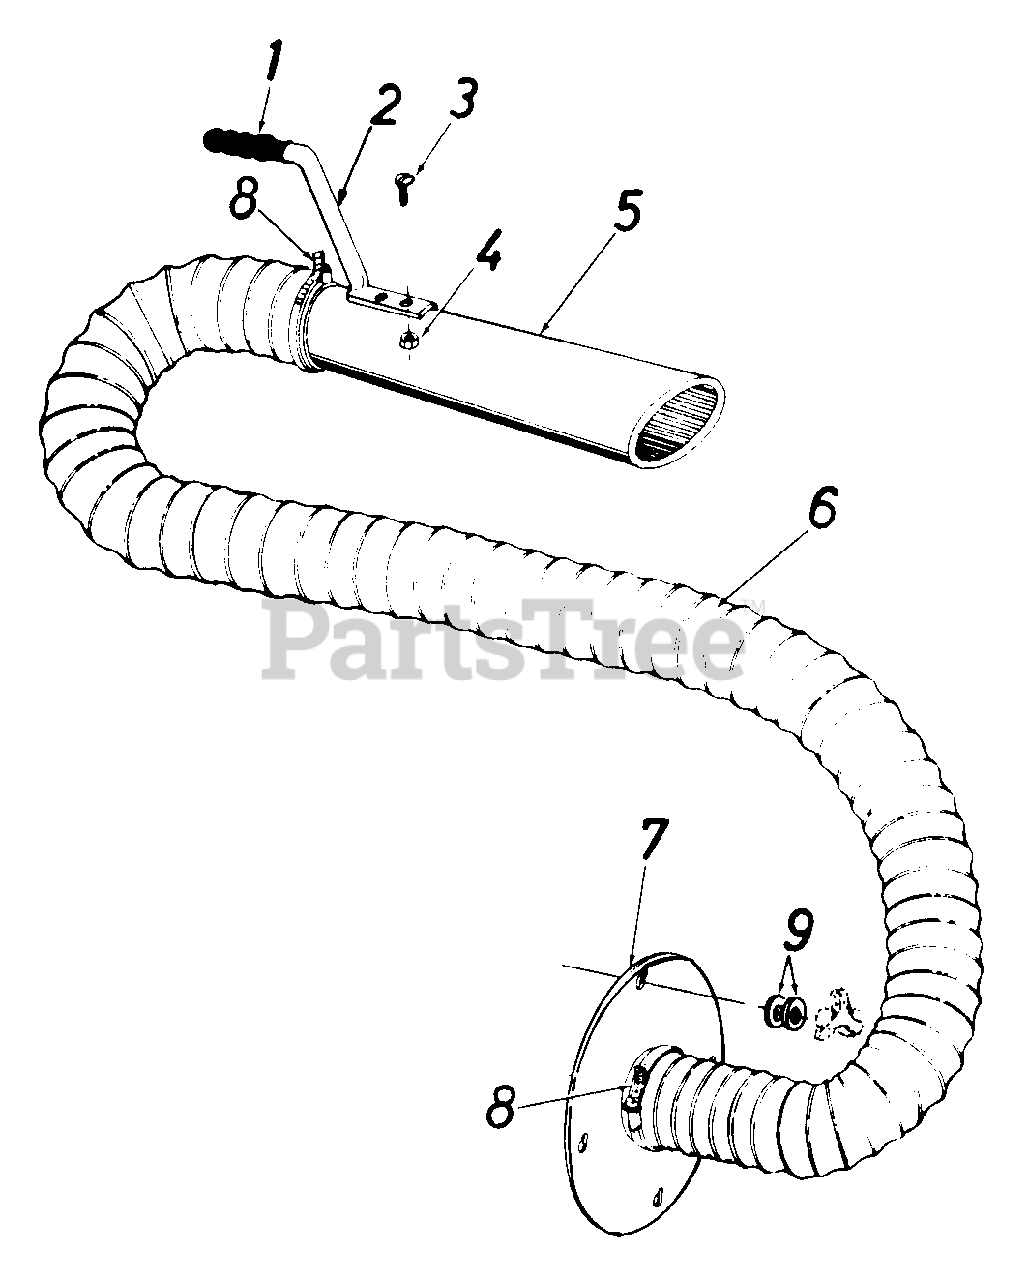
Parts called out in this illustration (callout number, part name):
1	Handle Grip
3	Truss Sems Scr. 10-24 x 1/2" Lg.
4	Hex Nut 10-24 Thd.
6	Flexible Hose 4" Dia. x 10' Lg.
9	Flat Washer .34 I.D. x 1.12 O.D.
